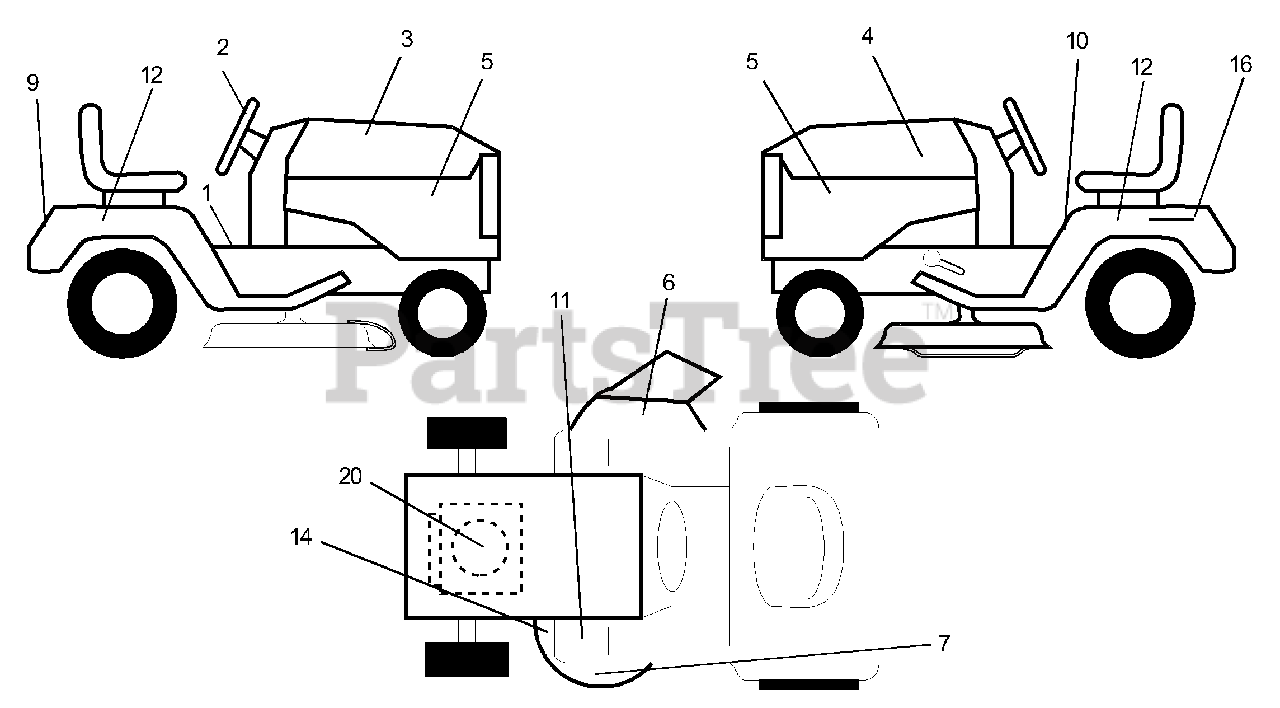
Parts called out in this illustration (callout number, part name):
1	Decal Instruction Operat Eng/Fre
2	Decal Ins Strg Wh
3	Decal Hood Rh
4	Decal Hood Lh
5	Decal Panel Side Logo
6	Decal Warning
7	Decal Mower Enviro White
9	Decal Fender Logo
10	Decal Danger English
11	Decal Clutch/brake English/French
12	Decal Fender
14	Decal V-belt Schematic 38"
16	Decal Battery Danger/Poison
20	Decal HP Engine
